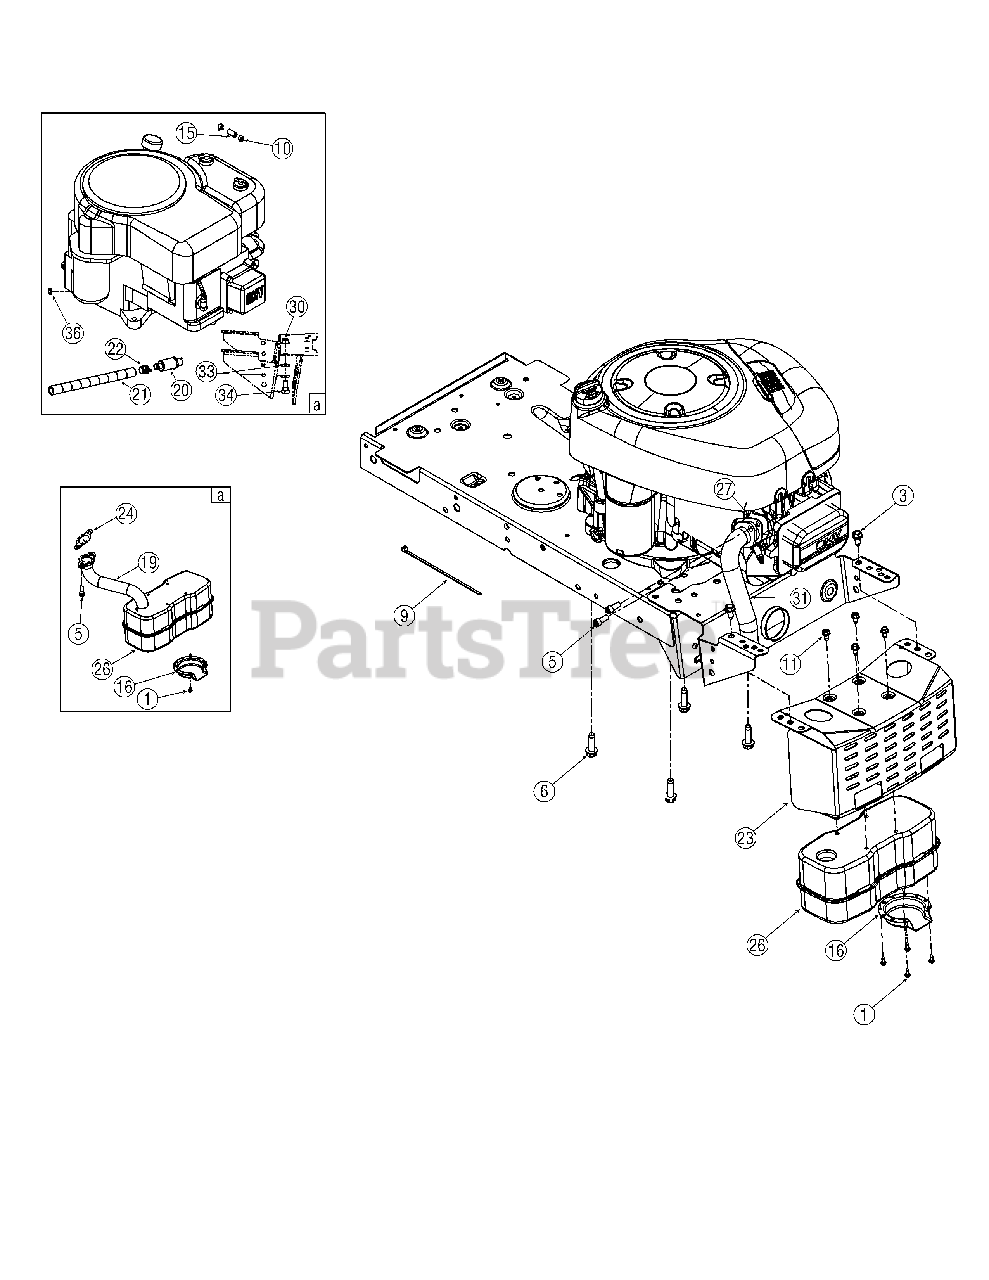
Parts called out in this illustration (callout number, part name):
1	Screw, #8-18 x .50
5	Socket Cap Screw, 5/16-18,.625
6	Self-tapping Screw, 3/8-16, 1.25
9	Cable Tie, 7.4"
10	Hose Clamp, .490
11	Screw, 1/4-20, 0.500
15	Fuel Line Hose
16	Muffler Deflector
20	Oil Drain Valve
21	Oil Drain Hose
22	Oil Drain Cap
24	Exhaust Gasket
26	Muffer, Single Inlet
27	Exhaust Gasket
30	Flange Lock Nut, 3/8-16
33	Flat Washer, .406 x .875 x .059
34	Shldr Screw, .498 x .340 x 3/8-16
36	Hex Sems Nut, 1/4-20
